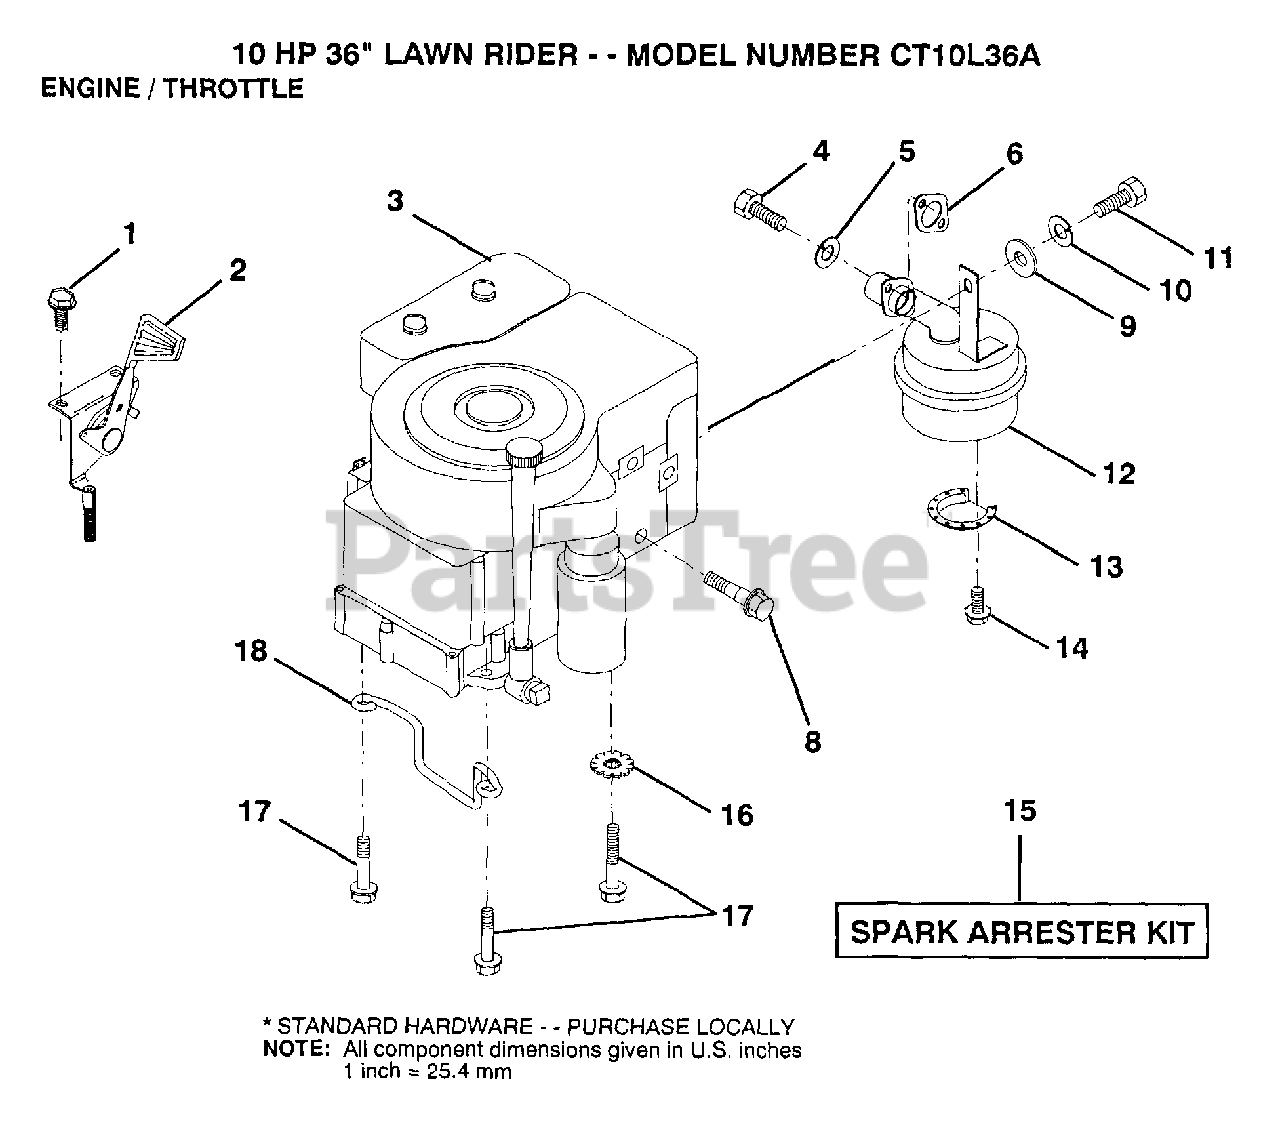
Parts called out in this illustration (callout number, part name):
1	SCREW
2	THROTTLE CONTROL
4	SCREW
5	LOCKWASHER
10	LOCKWASHER
12	MUFFLER
13	DEFLECTOR.222573
16	LOCKWASHER
17	SCREW LT
18	"KEEPER,DR BELT GR"
